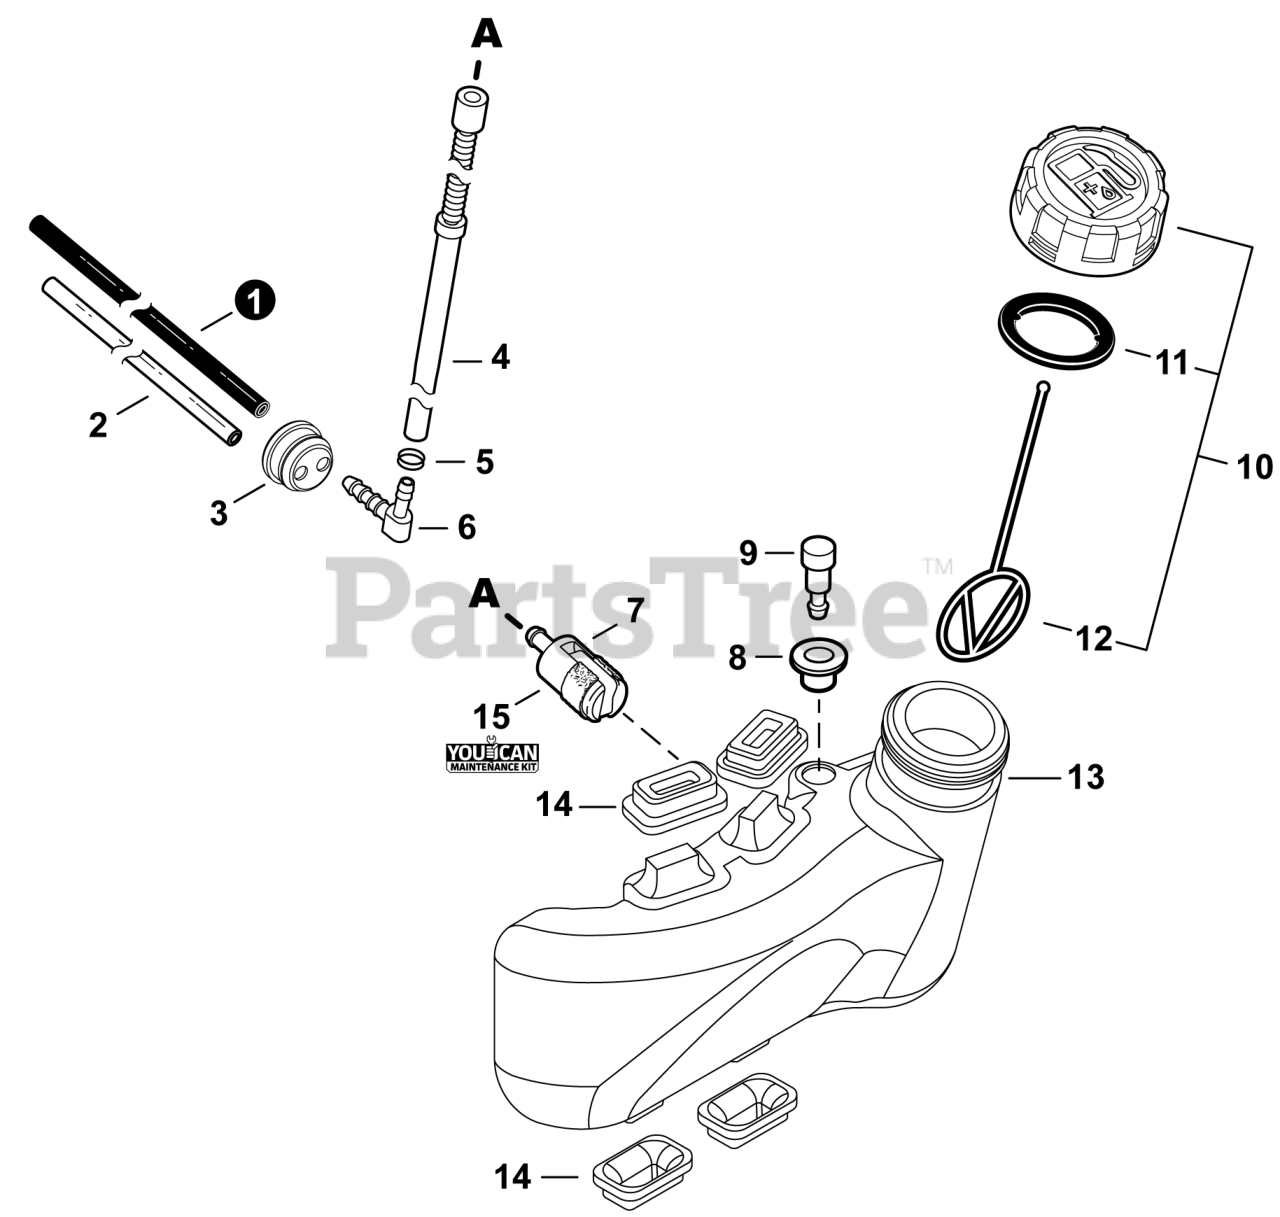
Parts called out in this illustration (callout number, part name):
1	PIPE, FUEL 3x5.5x83 BLACK
2	PIPE, FUEL 3x6x85 CLEAR
3	GROMMET, FUEL
4	PIPE, FUEL
5	CLIP 6.5 MM
6	CONNECTOR, PIPE
7	FILTER, FUEL
8	GROMMET, FUEL
9	VENT ASSY
10	CAP ASSY, FUEL
11	GASKET, FUEL CAP
12	CONNECTOR, CAP L= 123
13	TANK, FUEL
14	CUSHION
15	TUNE-UP KIT - YOUCANT
